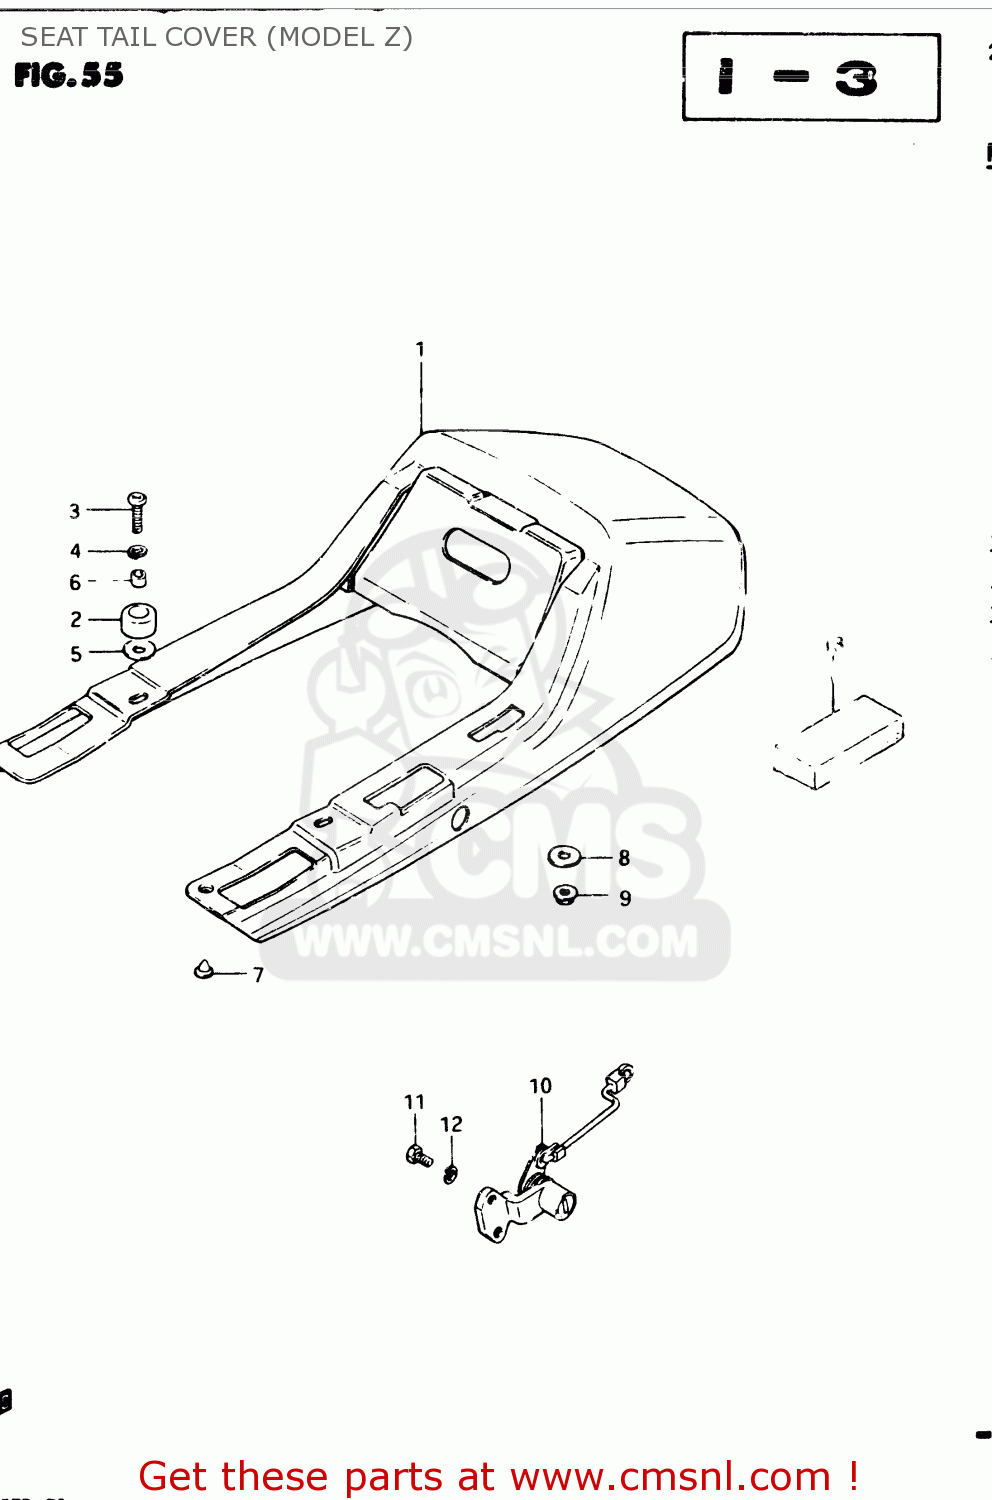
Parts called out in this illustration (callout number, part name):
1	TAIL COVER, SEAT (RED)
2	CUSHION,COVER
3	SCREW
4	LOCK WASHER
5	WASHER (6.5X24X1.6)
6	SPACER
7	CUSHION
8	WASHER
9	NUT 6MM
10	LOCK ASSEMBLY,SEAT
11	BOLT 5X10
12	LOCK WASHER
13	CUSHION
